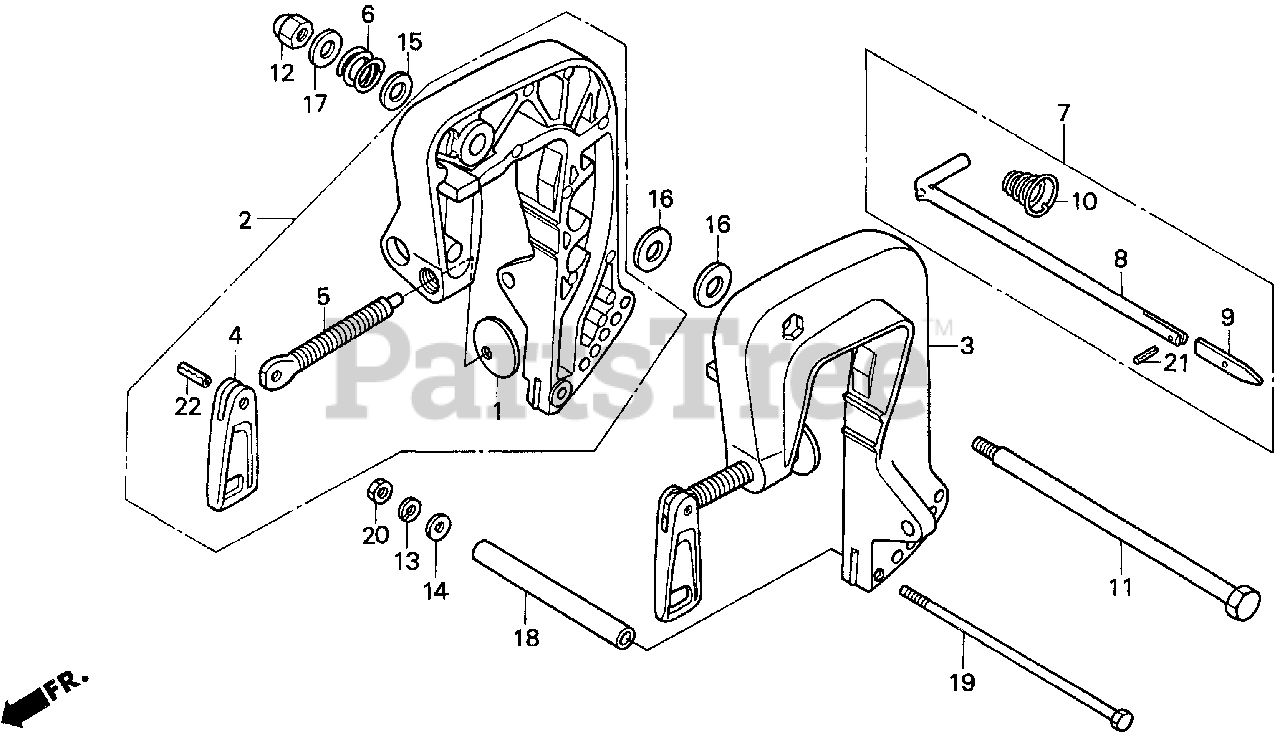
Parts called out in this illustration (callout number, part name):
1	PLATE, PUSH
2	BRACKET, R. STERN *NH210MC* (AQUA SILVER METALLIC-C)
3	BRACKET, L. STERN *NH210MC* (AQUA SILVER METALLIC-C)
4	GRIP, CLAMP *NH210MC* (AQUA SILVER METALLIC-C) (NOT AVAILABLE)
5	SCREW, CLAMP
6	SPRING, TILT
7	ROD, ADJUSTING
8	ROD, ADJUSTING
9	STOPPER, ROD
10	SPRING, ADJUSTING ROD
11	BOLT, TILTING
12	NUT, SELF-LOCK (8MM) (NOT AVAILABLE)
13	WASHER, SPRING (6MM)
14	WASHER, PLAIN (6MM)
15	WASHER, PLAIN (10MM)
16	WASHER (10MM)
17	WASHER (8MM)
18	COLLAR, DISTANCE (6MM)
19	BOLT, HEX. (6X160)
20	NUT, HEX. (6MM)
21	PIN, SPRING (2X8)
22	PIN, SPRING (4X14)
